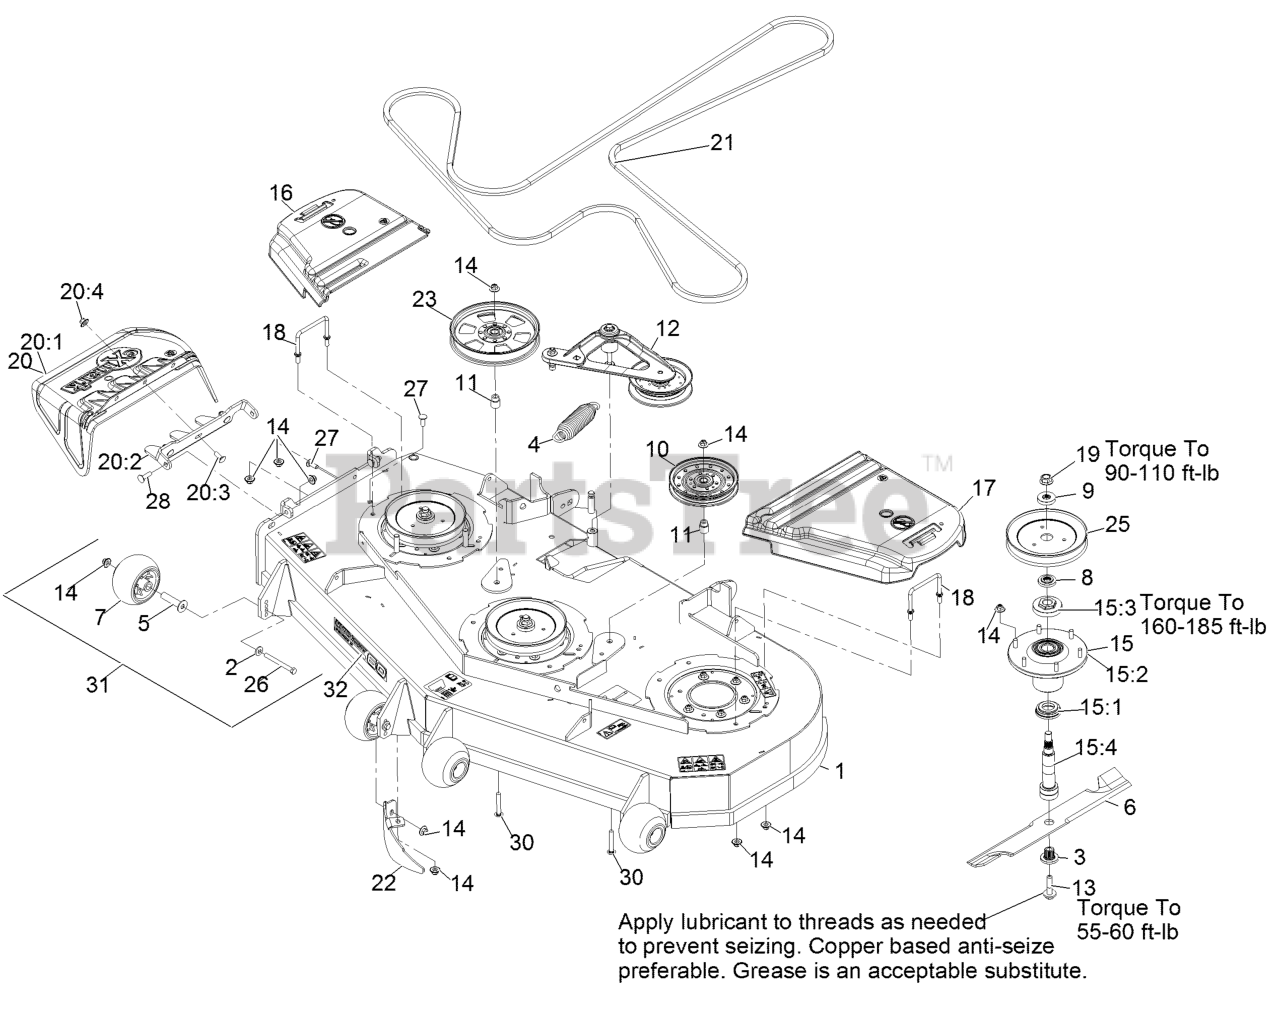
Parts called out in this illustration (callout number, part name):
1	DECK ASM,W/DECALS 60
2	WASHER-BELLEVILLE
3	BUSHING,SPLINED
4	SPRING-EXTENSION
5	AXLE, ROLLER
6	Blade-Extreme 2, 20.50"
7	ROLLER-SCALP, ANTI
8	SPACER,SPLINED STEPPED
9	SPACER,SPLINED
11	BUSHING-IDLER
12	DECK IDLER ASM
13	SCREW,SEMS 1/2-20 X 2.19
14	Nut-Nyloc 3/8-16 Flg
15	ASM,SPINDLE HOUSING
15:1	GUARD,BOTTOM
15:2	ASM,CUTTER HOUSING
15:3	NUT, SPINDLE 7/8-14
15:4	SPINDLE,DOUBLE SPLINE
16	COVER-BELT, RH
17	COVER-BELT, LH
18	WIREFORM-COVER
19	NUT-FLANGE, CENTERLOCK
20	ASM,DISCHARGE CHUTE
20:1	CHUTE,DISCHARGE
20:2	BRACKET,DISCHARGE CHUTE
20:3	SCREW-CARR
20:4	Nut-Nyloc 3/8-16 Flg
21	BELT,V-5V-198.75
22	DOGLEG - LZ60
23	PULLEY-IDLER, FLAT
25	SHEAVE,BLADE DRIVE 7.25
26	SCREW-HH 3/8-16 X 3 3/4 GR 8
27	SCREW-CARR
28	Bolt-Carriage 3/8-16 X 1 1/4
30	SCREW-CARR
31	KIT, ANTI-SCALP ROLLER
32	DECAL, 606
